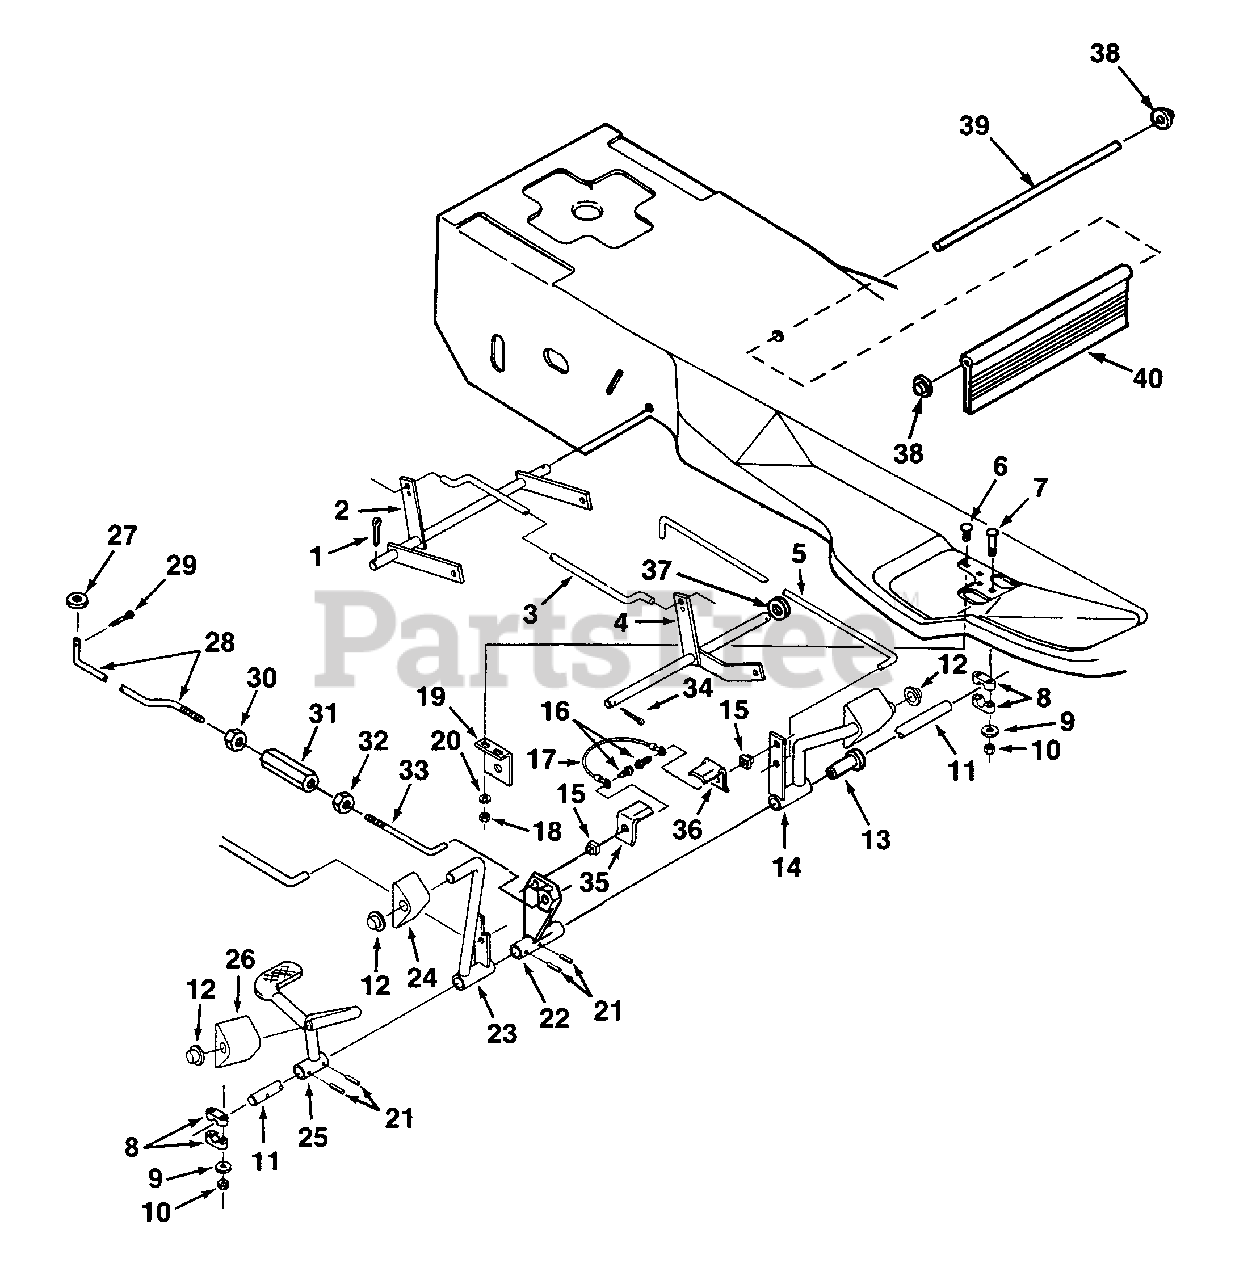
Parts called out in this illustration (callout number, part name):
3	ROD- Connecting
5	ROD- Clutch
9	WASHER
14	PEDAL ASSY-PTO
17	HARNESS-
18	NUT
22	LEVER- Traction
23	PEDAL ASSY- Brake
25	TREADLE & REVERSE
27	WASHER- Flat
28	ROD- Traction
31	TURNBUCKLE
33	ROD- Traction
40	FLAP- Drag
